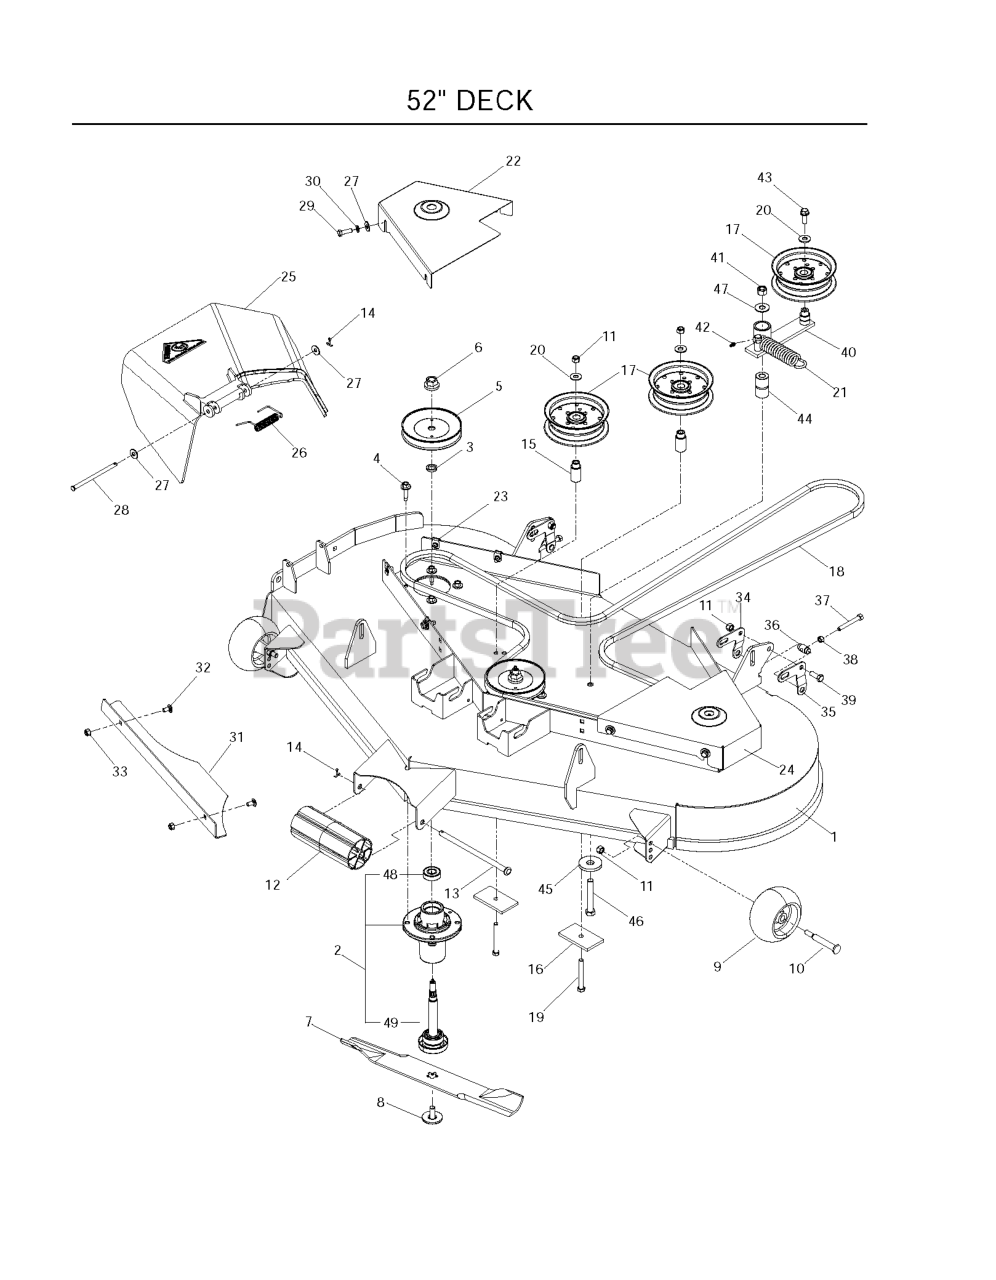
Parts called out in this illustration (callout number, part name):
1	DECK.FAB.W/DECALS.52".MZ.ORANG
2	MANDREL.DECK.ASSEMBLY
3	WASHER-SPACER
4	WASHER HEAD SCREW
5	PULLEY
6	LOCKNUT - 9/16
7	BLADE, 18"
8	BLADE BOLT ASSY-7/16" TB REPL
9	GAUGE WHEEL
10	SHOULDER BOLT 1/2X2-5/8 ZD SPE
11	NUT 3/8-16 NYLOC
12	NOSE ROLLER 48"
13	NOSE ROLLER ROD
14	RP_COTTER PIN 1/8 X 3/4
15	IDLER BUSHING
16	SUPPORT PLATE
17	PULLEY, IDLER
18	BELT.DECK.52".54"
19	HCS 3/8C X 3
20	WASHER 3/8 FLAT
22	BELT SHIELD, RIGHT 52, ORG
23	U-CLIP 5/16-18 NUT RETAINER
24	BELT SHIELD, LEFT 52, ORG
25	DISCHARGE CHUTE 52"
26	SPRING - TORSION
27	WASHER 5/16 FLAT
28	PIN-CLEVIS 5/16 DIA X 5.19 ZD
29	HCS 5/16C X 1
30	WASHER.LOCK.HVY.HLCL.SPR.5/16
31	CONFINEMENT PLATE, 52"
32	CARRIAGE BOLT 5/16C X 5/8"
33	NUT 5/16 NYLOC
34	PITCH, ADJUST, RT
35	PITCH, ADJUST, LT
36	TRUNION, PITCH
37	HCS 5/16-18 X 2 1/2 TPBLT
38	NUT 5/16C HEX
39	HCS 3/8-16X1.GRD.5.ZD
41	NUT 1/2-13 HEX NYLOC ZD
42	ZERK
43	4CS 3/8C X 1 SERRATED HEAD
44	PIVOT BUSHING
45	WASHER, SUPPORT
46	HCS 1/2C X 3 1/4
47	WASHER 1/2 FLAT
48	BEARING, BALL
49	GREASABLE MANDREL SHAFT
